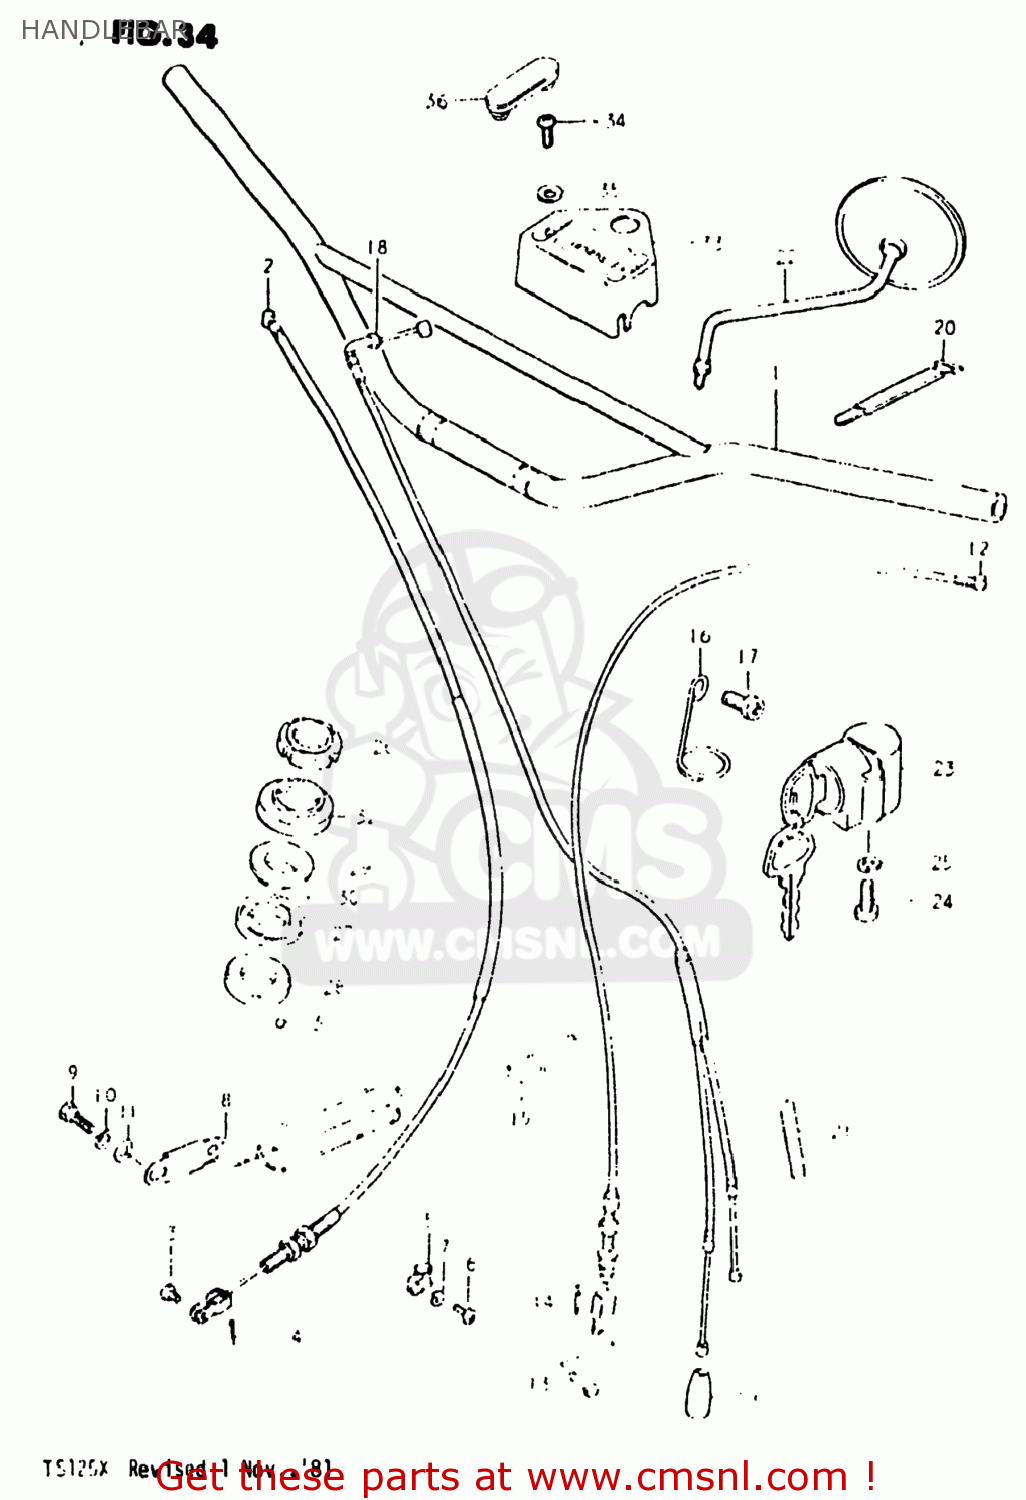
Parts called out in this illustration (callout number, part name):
1	HANDLEBAR
2	CABLE,FR BRAKE
3	PIN(L:13.5)
4	PIN
5	GUIDE,CABLE
6	SCREW
7	LOCK WASHER
8	GUIDE,CABLE
9	BOLT 8X12
10	LOCK WASHER
11	WASHER
12	CABLE ASSEMBLY,CLUTCH
13	PIN(L:15)
14	PIN
15	CLAMP
16	CLIP
17	SCREW
18	CABLE ASSEMBLY,THROTTLE
19	SEAL,DUST(7X18X30)
20	CLAMP L:110
21	PROTECTOR,CABLE
22	MIRROR ASSEMBLY,LEFT
23	LOCK ASSEMBLY,STEERING
24	SCREW
25	LOCK WASHER
26	NUT,STEERING STEM(25X44X10)
27	RACE,STEERING INNER UPR
28	LACE,STEERING INNER LWR
29	RACE,STEERING OUTER UPR
30	BALL
31	BALL
32	DUST SEAL,STEERING UPR
33	COVER,STEERING HEAD
34	SCREW 6X12
35	WASHER
36	CAP,PILOT BOX BOLT
